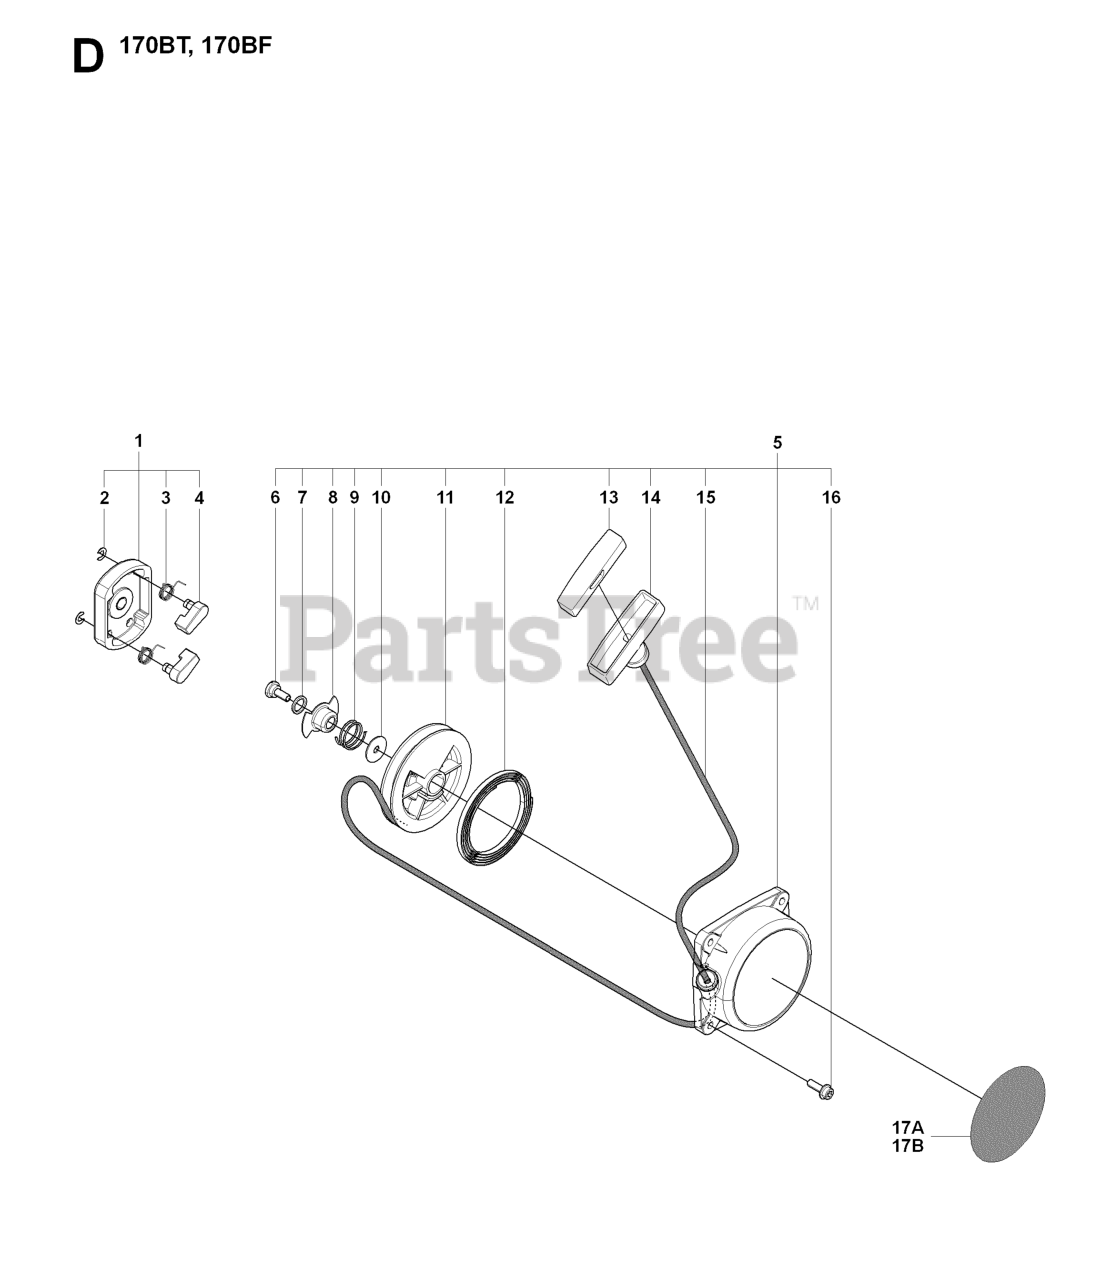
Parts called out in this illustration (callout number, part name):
1	PULLEY ASSY
5	RECOIL ASSY
9	SPRING FRICTION
10	WASHER
14	KNOB
15	ROPE
17A	LABEL.RECOIL
